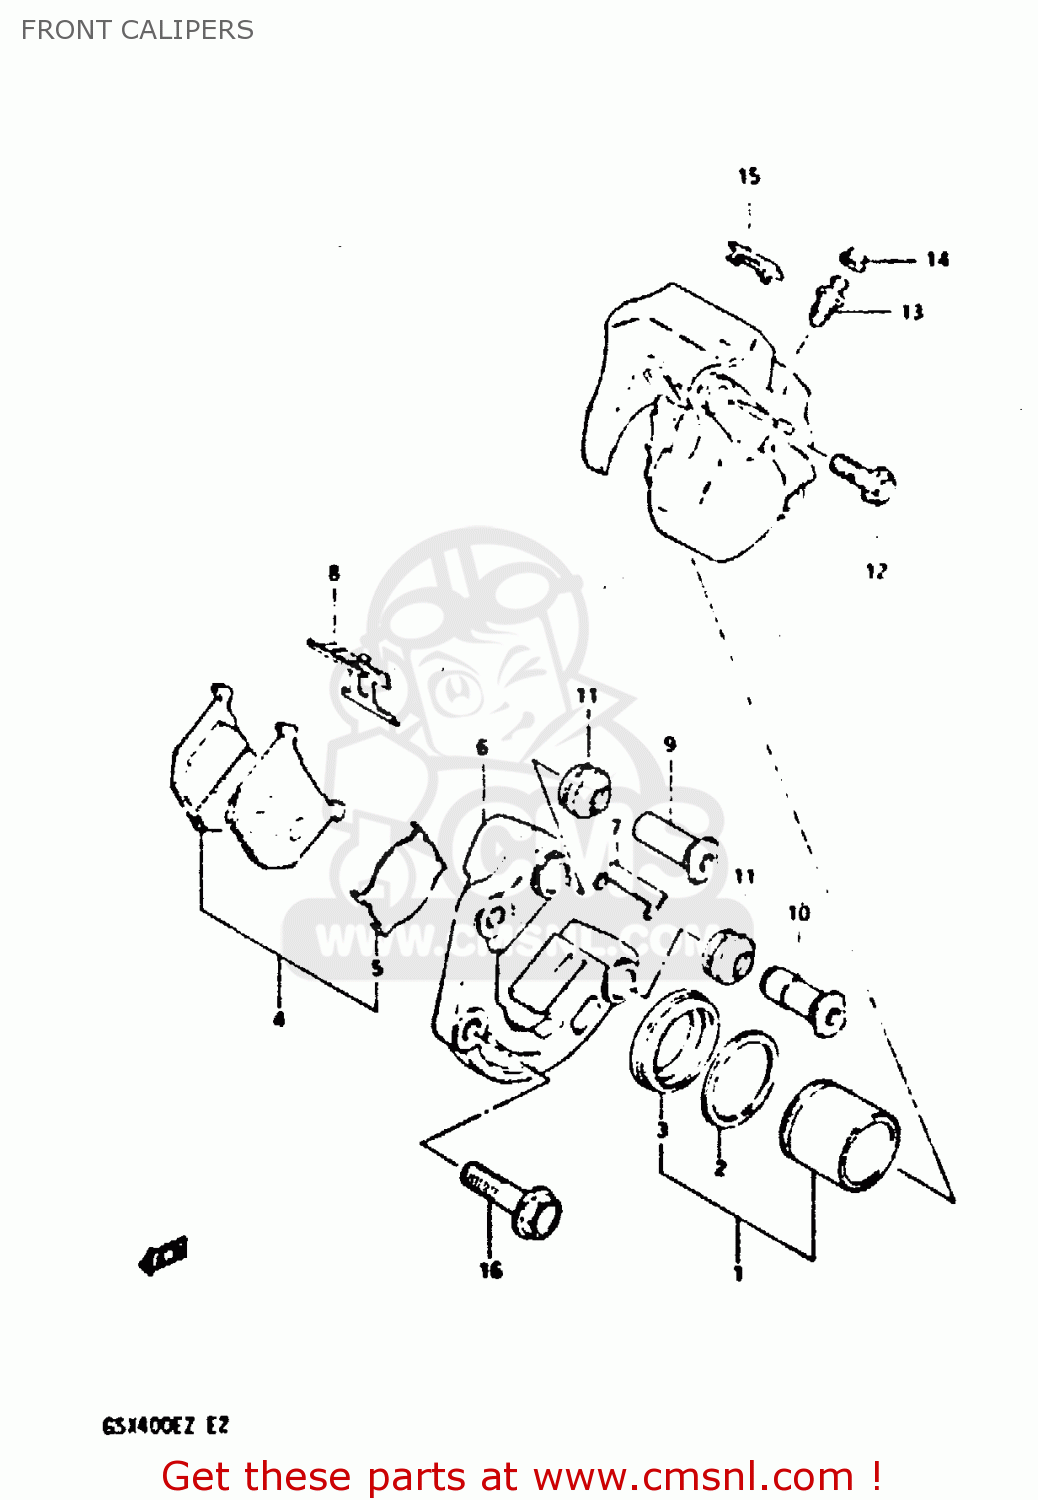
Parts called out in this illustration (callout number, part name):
1	PISTON SET
2	SEAL,FR CALIPE
3	BOOT,PISTON
4	PAD SET,BRAKE (MCA)
5	SHIM,PAD
6	CARRIER,CALIPER,LEFT
7	GUIDE,PAD
8	SPRING,PAD
9	AXLE NO.1
10	AXLE NO.2
11	BOOT,AXLE
12	BOLT,CALIPER HOUSING
13	BLEEDER
14	CAP,BREATHER
15	COVER
16	BOLT 10X37
